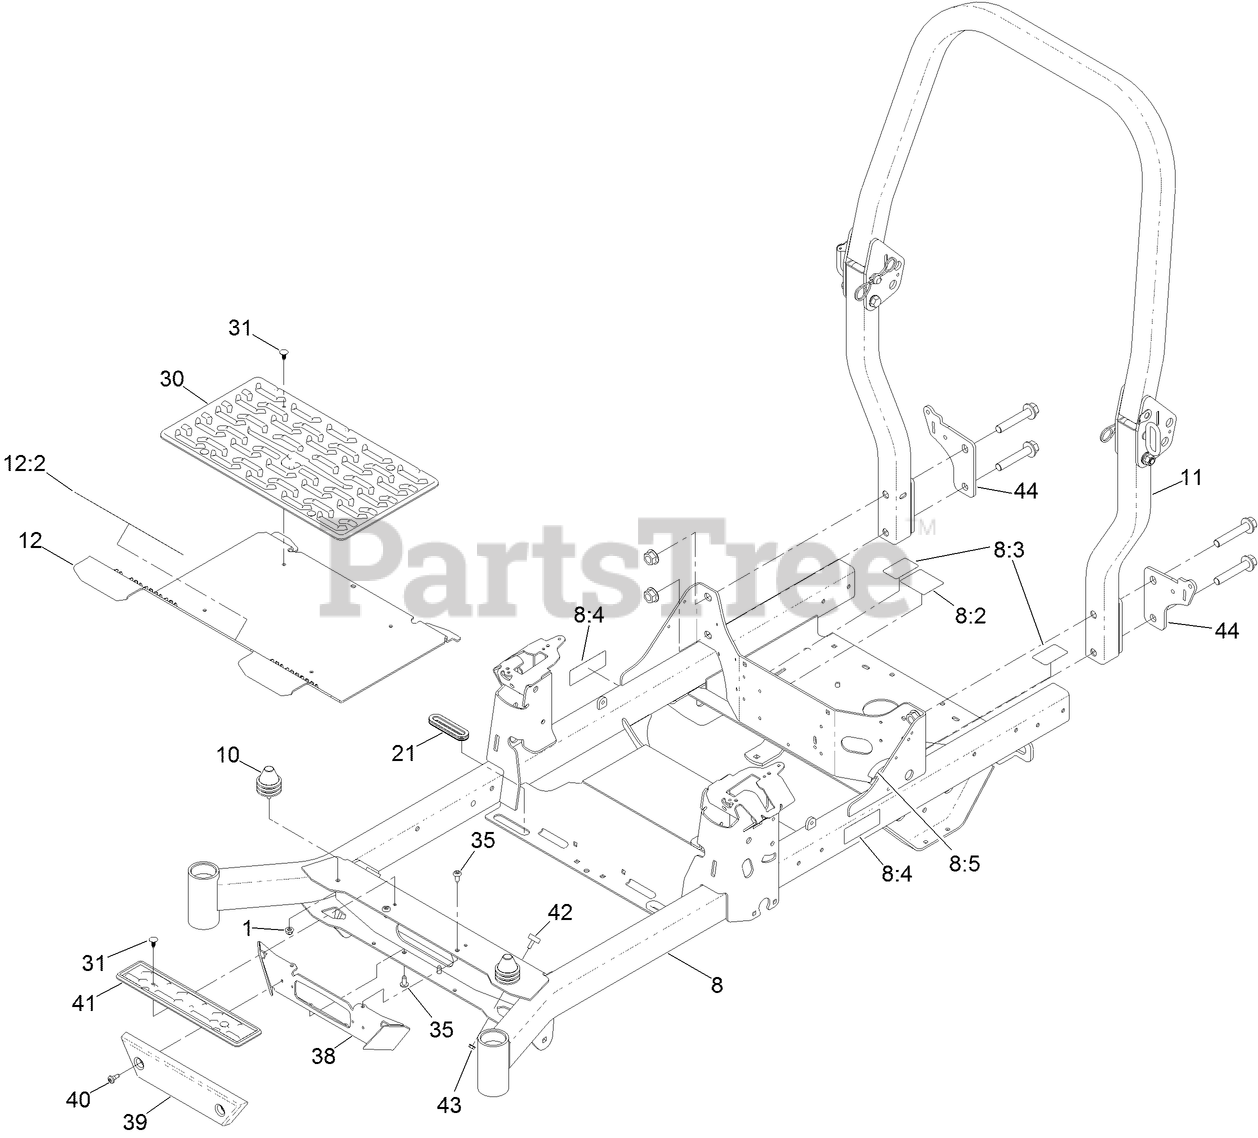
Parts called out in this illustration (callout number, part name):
1	NUT-HF, NI
8	FRAME-48/52
8:2	DECAL-ROUTING, BELT
8:3	DECAL-RELEASE, DRIVE
8:4	DECAL-WARNING
8:5	STRIP-SEAL
10	ISOLATOR
11	ASM-ROPS
12	PAN-FLOOR
12:2	DECAL-DANGER
21	GROMMET-RUBBER
30	FLOOR MAT
31	PLUG-PLASTIC
38	BRACKET-LIGHT [RED]
39	BUMPER-FRONT
40	SCREW-SHOULDER
42	BUMPER-RUBBER
43	NUT-HF
